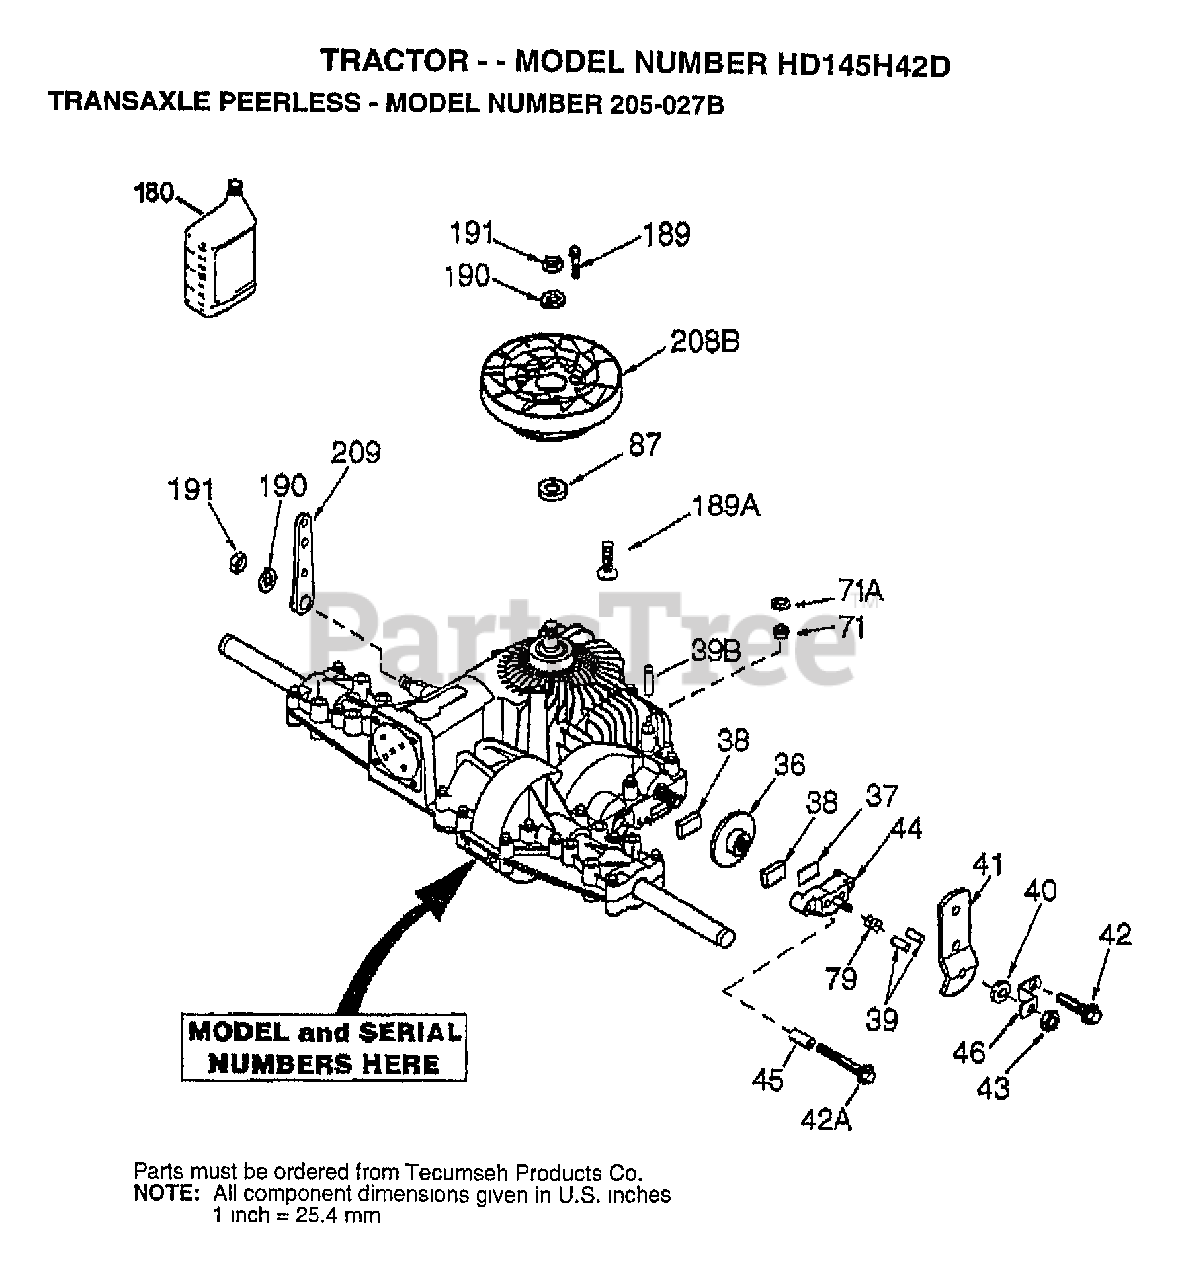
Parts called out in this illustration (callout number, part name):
37	PLATE BRAKE PAD
41	BRAKE LEVER
42	SCREW, 1/4-20 X 1-1/4
42A	SCREW, 1/4-20 X 2-1/4
43	LOCKNUT 5/16-24
44	HOLDER BRAKE PAD
46	BRAKE LEVER BRACKET
71	SEAL SQUARE CUT
180	GEAR OIL 80W90
189	DRIVE SCREW
208B	FAN/COUPLING
209	CONTROL LEVER
